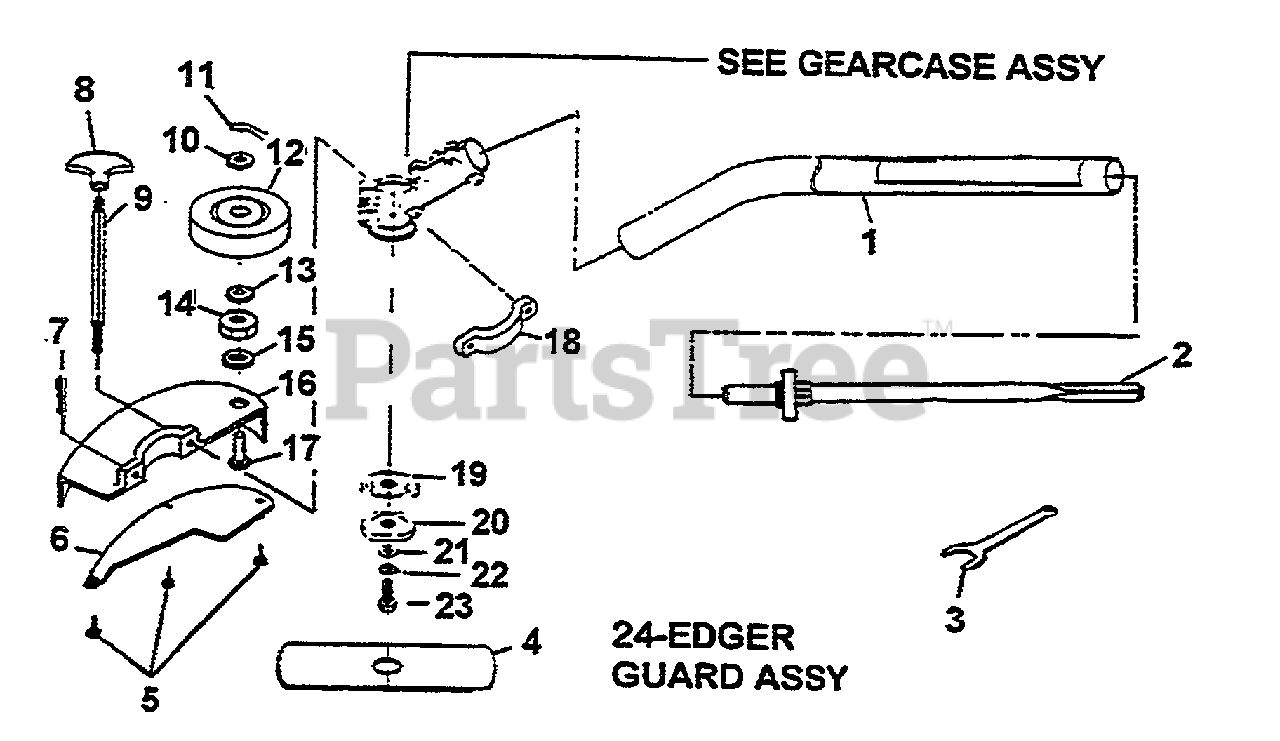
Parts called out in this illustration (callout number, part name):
1	TUBE ASSY
2	FLEX CABLE
3	SPANNER WRENCH
4	EDGER BLADE
5	SCREW
6	EDGER SHIELD
8	KNOB
9	SHAFT & KNOB KIT
11	COTTER PIN
14	NUT
16	EDGER GUARD
17	EDGER AXLE
20	HOLDER B
22	WASHER
23	BOLT
24	EDGER GUARD ASSY
